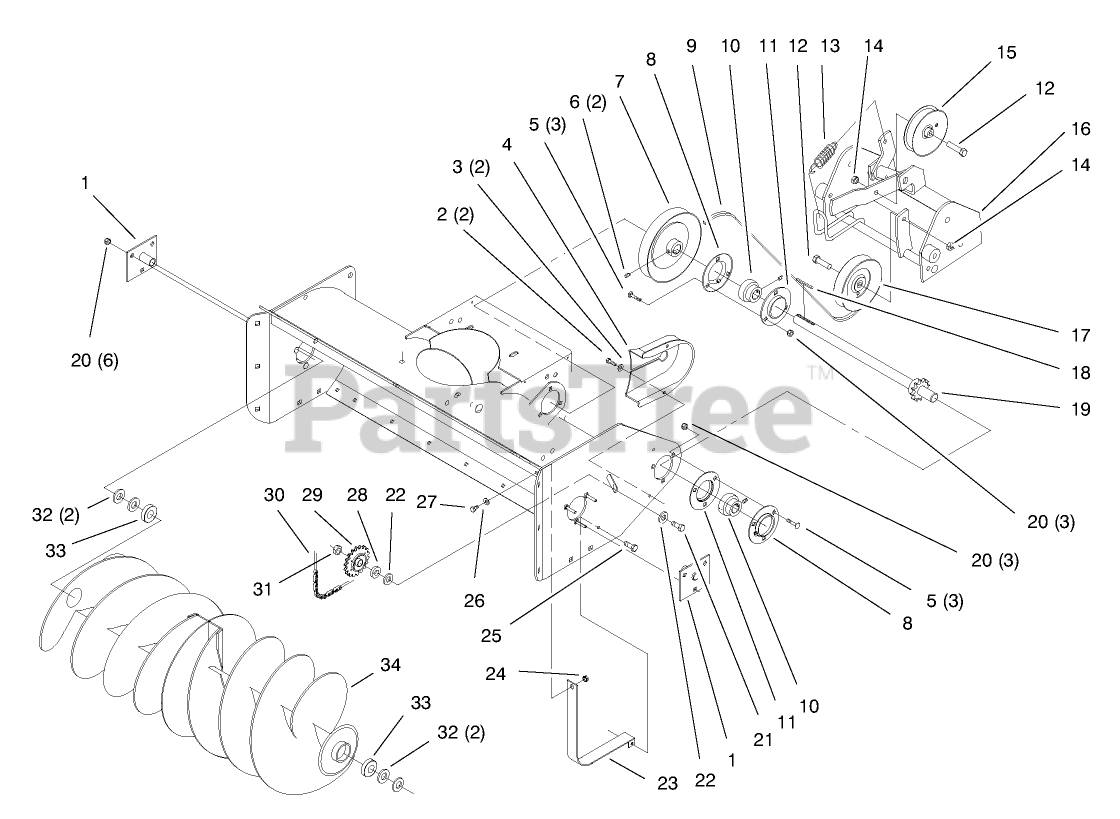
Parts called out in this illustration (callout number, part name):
1	SUPPORT ASM
2	SCREW-HWH
3	WASHER-FLAT
4	GUARD-CHAIN
5	BOLT-CARR
6	SCREW-SQH
7	PULLEY
8	FLANGE
9	V-BELT
10	BEARING AND COLLAR
11	FLANGE-ZERK RELUBE
12	SCREW-HH
13	SPRING-EXTENSION
14	NUT-LOCK, NI
15	PULLEY-IDLER
17	PULLEY-IDLER
20	NUT-LOCK, NI
21	SCREW-HH
22	WASHER-FLAT
23	GUARD-INNER
24	NUT-KEPS
26	WASHER-FLAT
27	SCREW-HH
28	SPACER
30	CHAIN
31	NUT-LOCK, NI
32	WASHER-FLAT
33	BEARING-BALL
